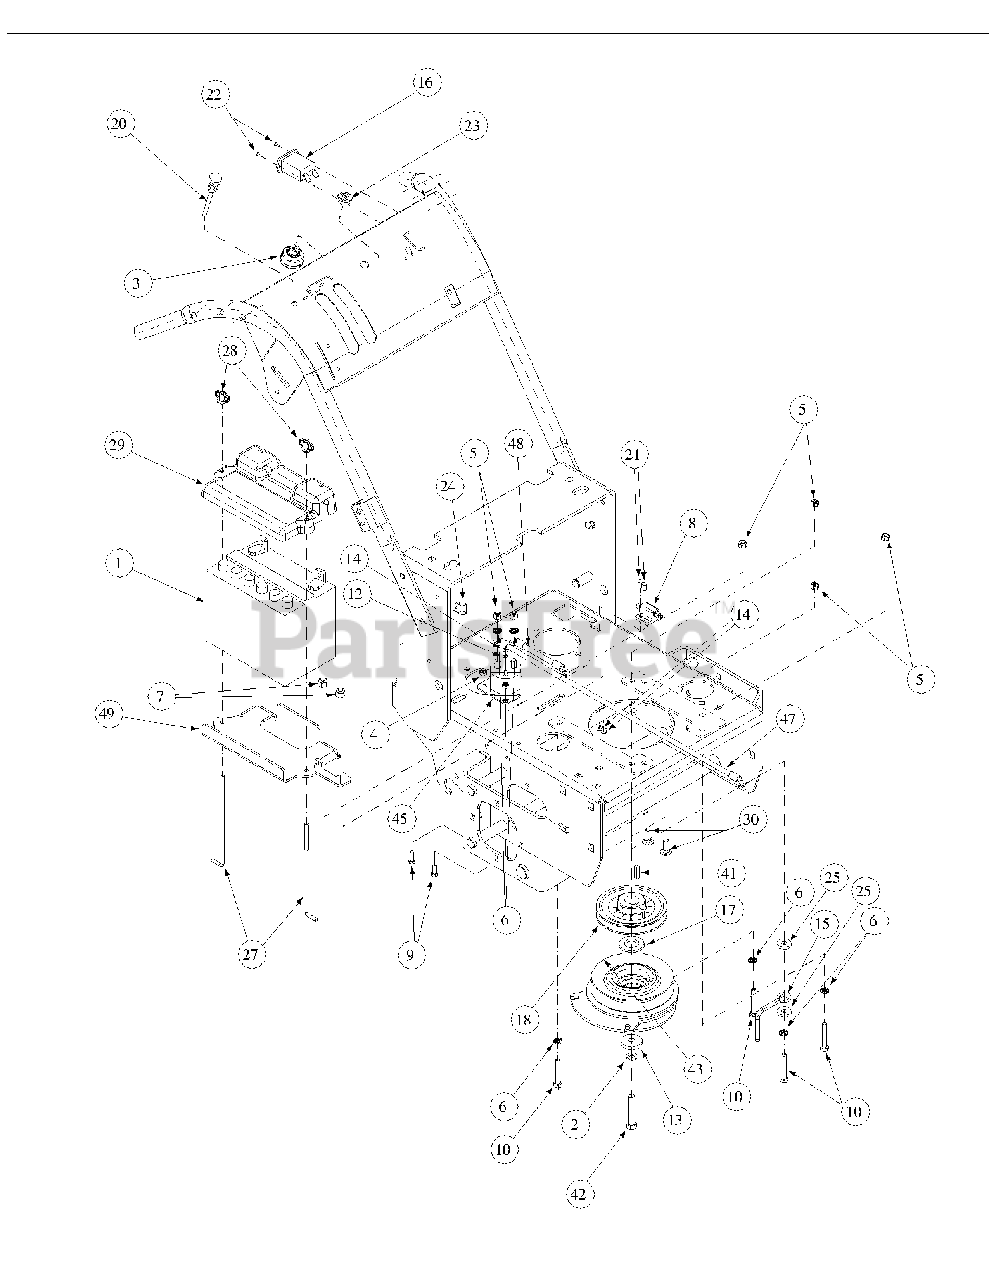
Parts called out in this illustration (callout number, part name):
1	Battery, 12V, 225CCA
2	Lock Washer M10
3	Ignition Switch
4	Lock Nut, Nylon Insert, 1/4-20
5	Nut, 5/16-18, Nylock
6	Lock Washer, 5/16
7	Lock Nut, Nylon Insert, 3/8-16
8	Switch, Delta
9	Cap Screw, 1/4-20 x .75
10	Cap Screw, 5/16-18 x 2
10	Boot, Battery Post Red
12	Lock Washer, #10
13	Washer Clutch
14	Lock Nut, Nylon Insert, #10-32
15	Guide, Track Drive Belt
16	Hour Meter
17	Washer, Special
18	Sheave 1" Bore w/2 Set Screws
18	Belt, Hydro Pump
20	Choke Cable
21	Phil. Hd. Mach. Screw, #10-32 x 5/8
22	Rivet
23	Nut, w/Cap, 5/8-32 Ignition
24	Support Clamp 3/8 OD
25	Washer, Idler
25	Battery Cable, 10" Black
27	Hold Down Rod, Battery
28	Wing Nut, 1/4-20 w/Bell Washer
29	Battery Cover, Large
30	Carriage Bolt, 3/8-16 x 2
30	Engine, 18hp Vertical
30	Capscrew, w/Lockwasher
30	Manifold
30	Muffler Clamp Assembly
30	Bracket, Muffler
30	Screw, M6 x 1.0 x 12mm
30	Screw, Hex Flange, M5 x 1.0 x 8mm
30	Bracket Debris Guard
30	Electric Debris Guard
41	Key, 1/4 x 1/4 x 1
42	Capscrew, M10-1.5 x 60 mm
43	Brake Clutch
43	Harness
45	Solenoid Magnetic Switch
45	Harness Adapter Assy
47	Battery Cable, Red 24"
48	Battery Cable, Red 5"
49	Battery Bracket
